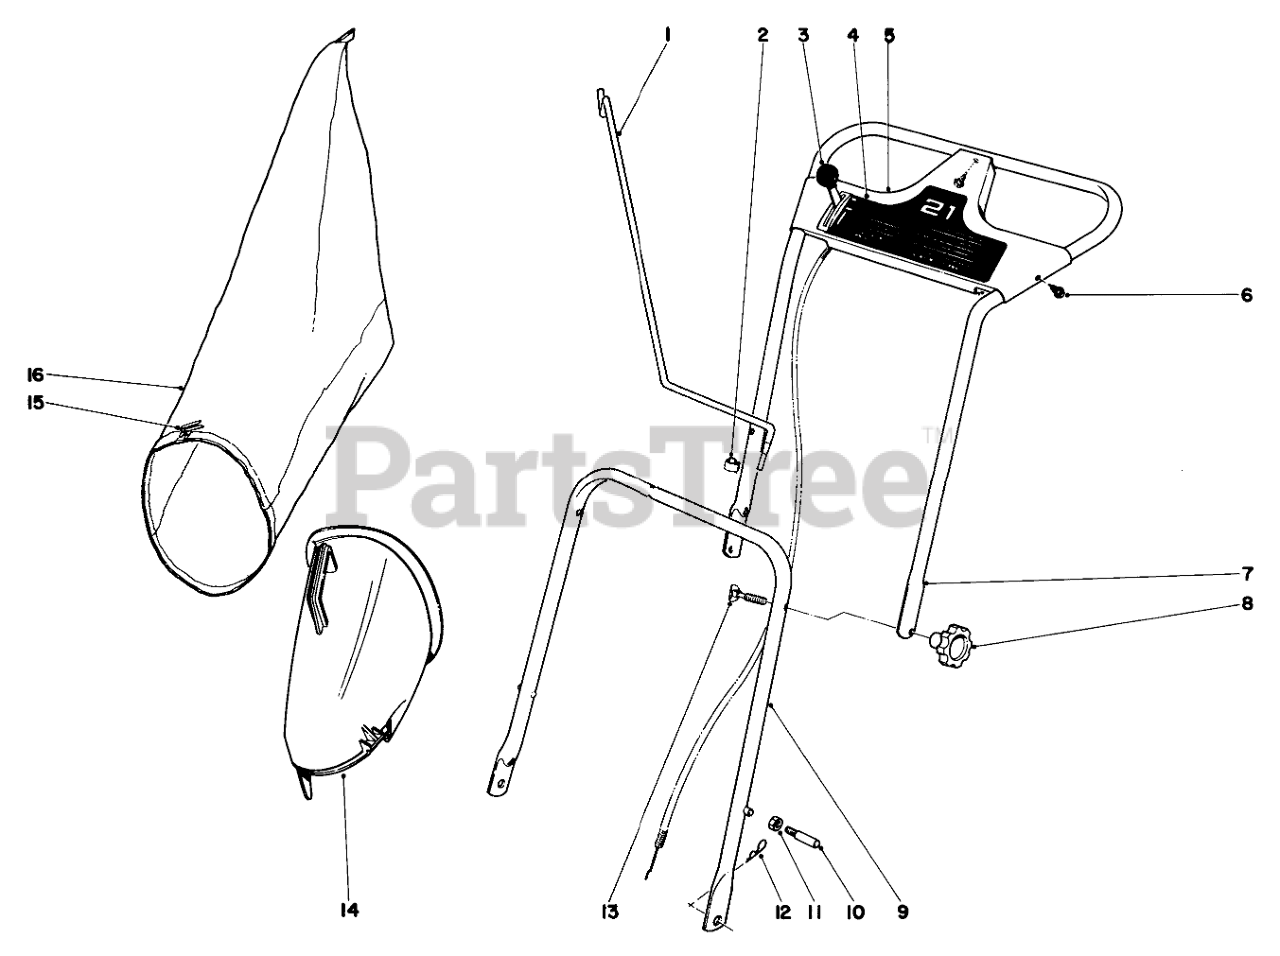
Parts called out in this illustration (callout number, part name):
1	Bag Hanger Rod
2	CONTROL WIRE CLIP
3	Throttle Control
4	Decal, Escutcheon Plate
5	Escutcheon Plate
6	Screw, Self Tapping
7	Upper Handle
8	Handle Release Knob
9	Lower Handle
10	Handle Pin
11	Nut
12	PIN-COTTER, HAIR
13	HANDLE SCREW
14	Bag Attachment
15	BAG CORD FASTENER
16	Grass Bag Kit
